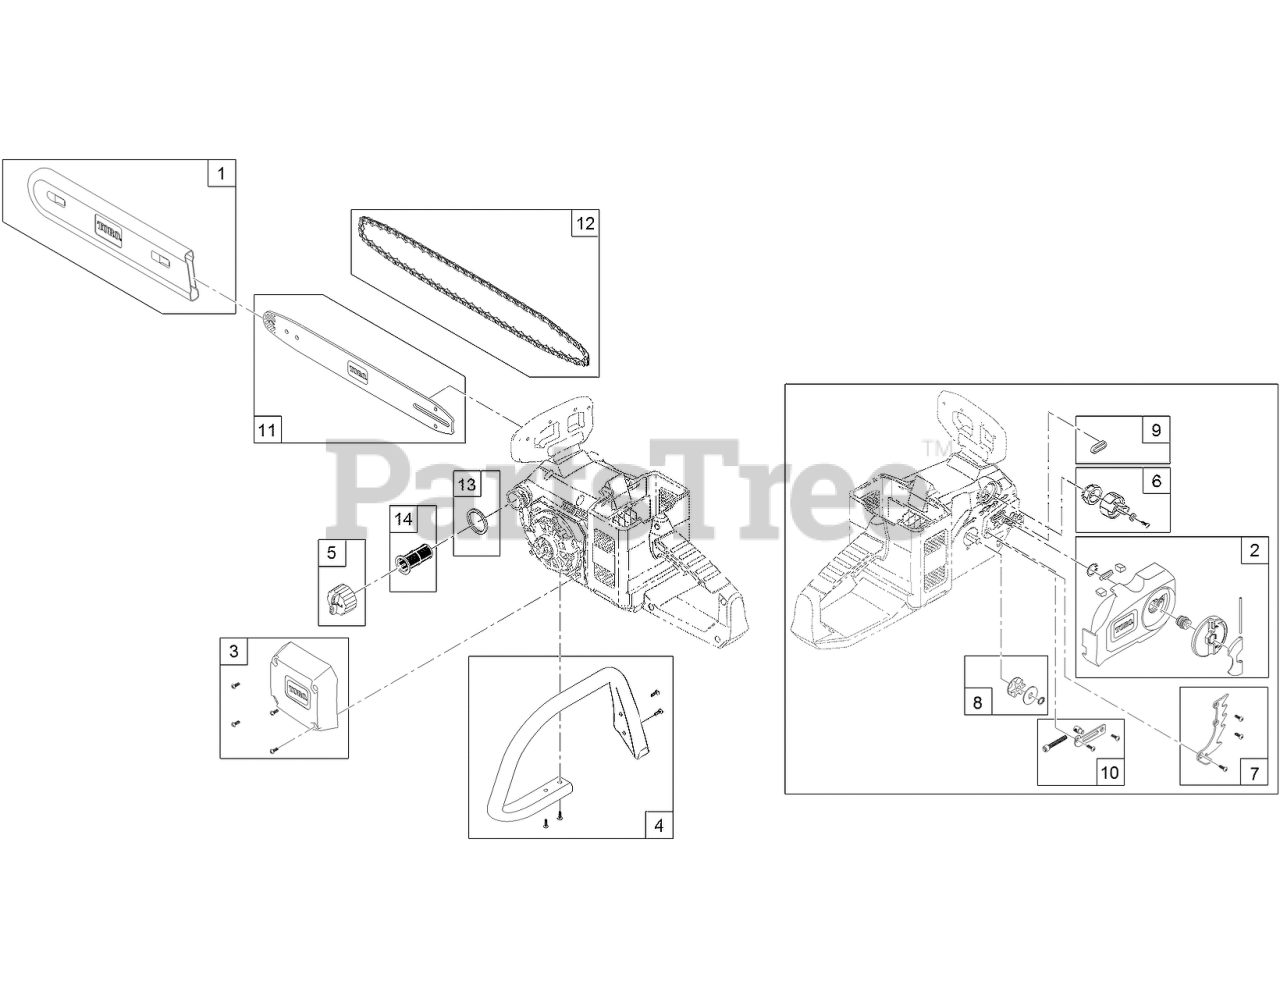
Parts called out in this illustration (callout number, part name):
1	SLEEVE-Bar/CHAIN
2	CHAIN Bar PANEL ASM
3	COVER-MOTOR
4	HANDLE
5	Cap-Oil, Bar
6	KNOB-ADJUSTER, Bar AND CHAIN
7	BUCKING TEETH BRACKET ASM
8	SPROCKET-DRIVE, CHAIN
9	GASKET-OIL, Bar/HOUSING
10	ADJUSTER-Bar PIN AND SCREW
11	Bar-REPLACEMENT
12	CHAIN
13	Gasket-Oil Cap, Bar
14	Strainer-Oil, Bar
